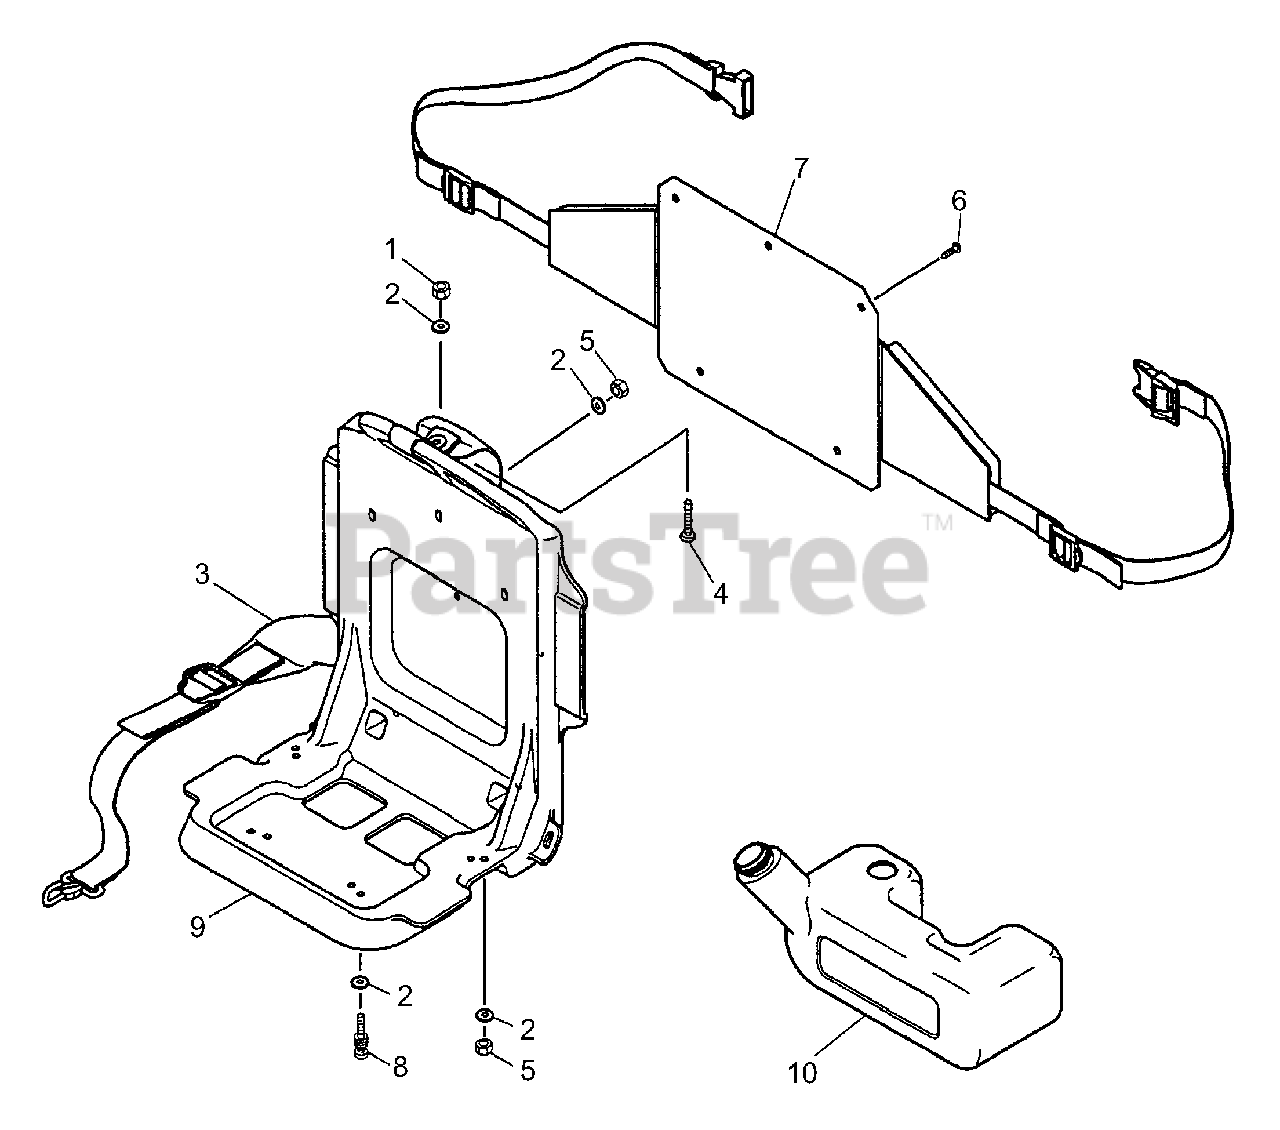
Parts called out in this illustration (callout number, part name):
1	Flange Nylon Nut (M6)
2	Washer
3	Shoulder Band
4	Truss Screw (M6x16)
5	U-Nut (M6)
6	Clip
7	Backpack Pad
8	Screw (M6x16)
9	Backpack Frame
10	Fuel Tank
